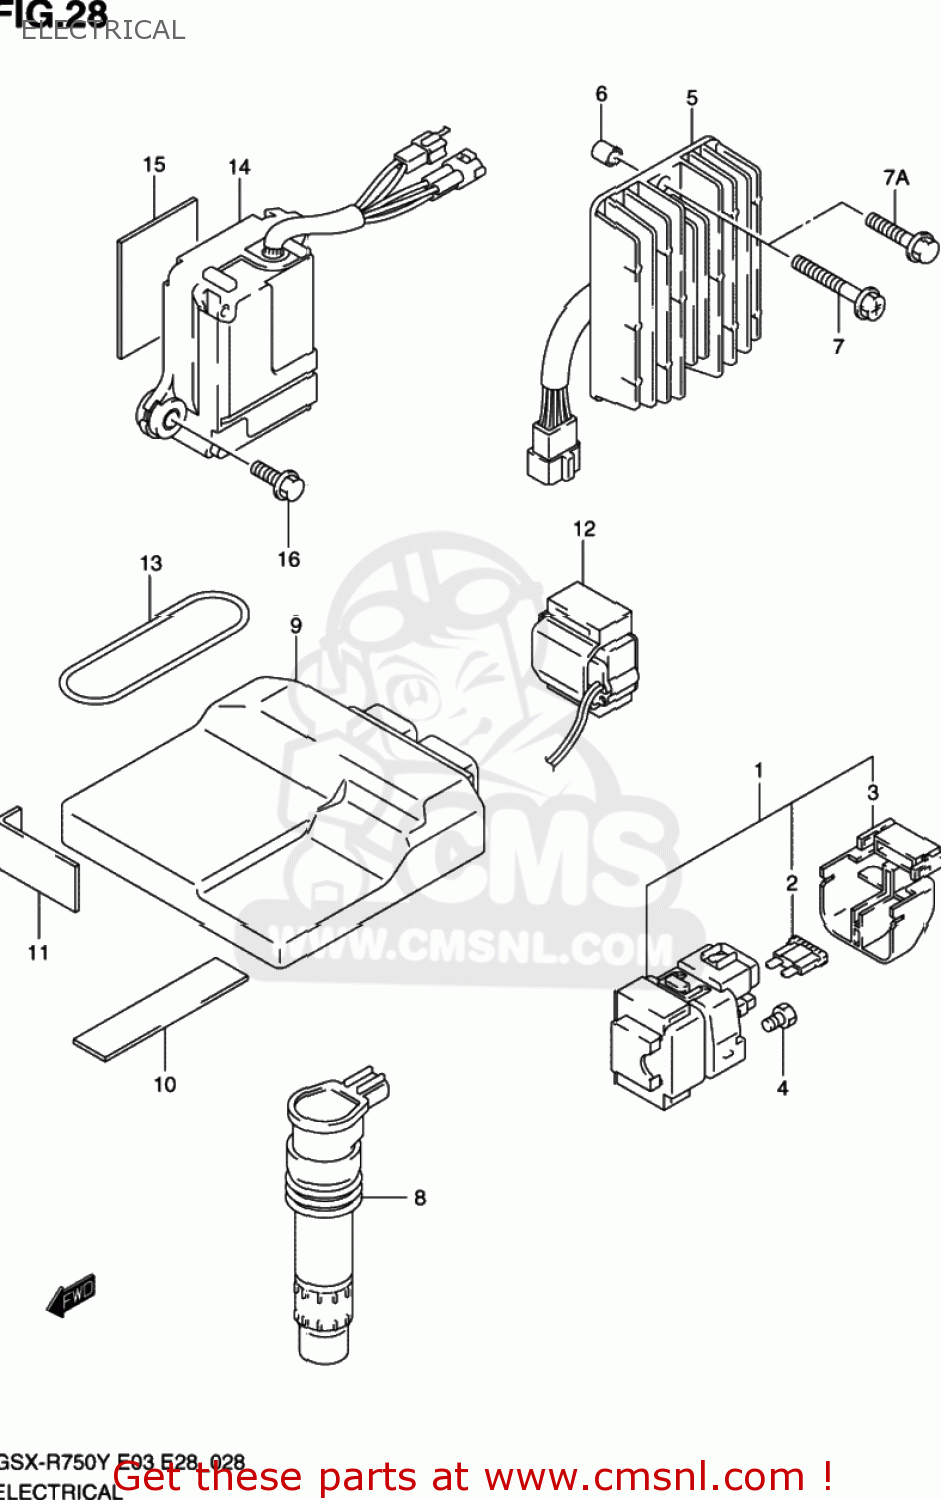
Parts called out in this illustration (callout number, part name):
1	RELAY ASSY,STARTING MOTOR
2	FUSE(30A)
3	COVER,STARTER RELAY
4	SCREW(6X8)
5	RECTIFIER ASY
6	SPACER(6.5X10X7)
7	SCREW
7A	BOLT
8	COIL ASSY,IGNITION
9	CONTROL UNIT,FI
10	PROTECTOR(80X80X2)
11	PROTECTOR(170X95X3.0)
12	SENSOR ASSY,FUEL CUT
13	O RING(D:3.53,ID:69.44)
14	ACTUATOR ASSY
15	PROTECTOR,ACTUATOR
16	BOLT(6X25)
